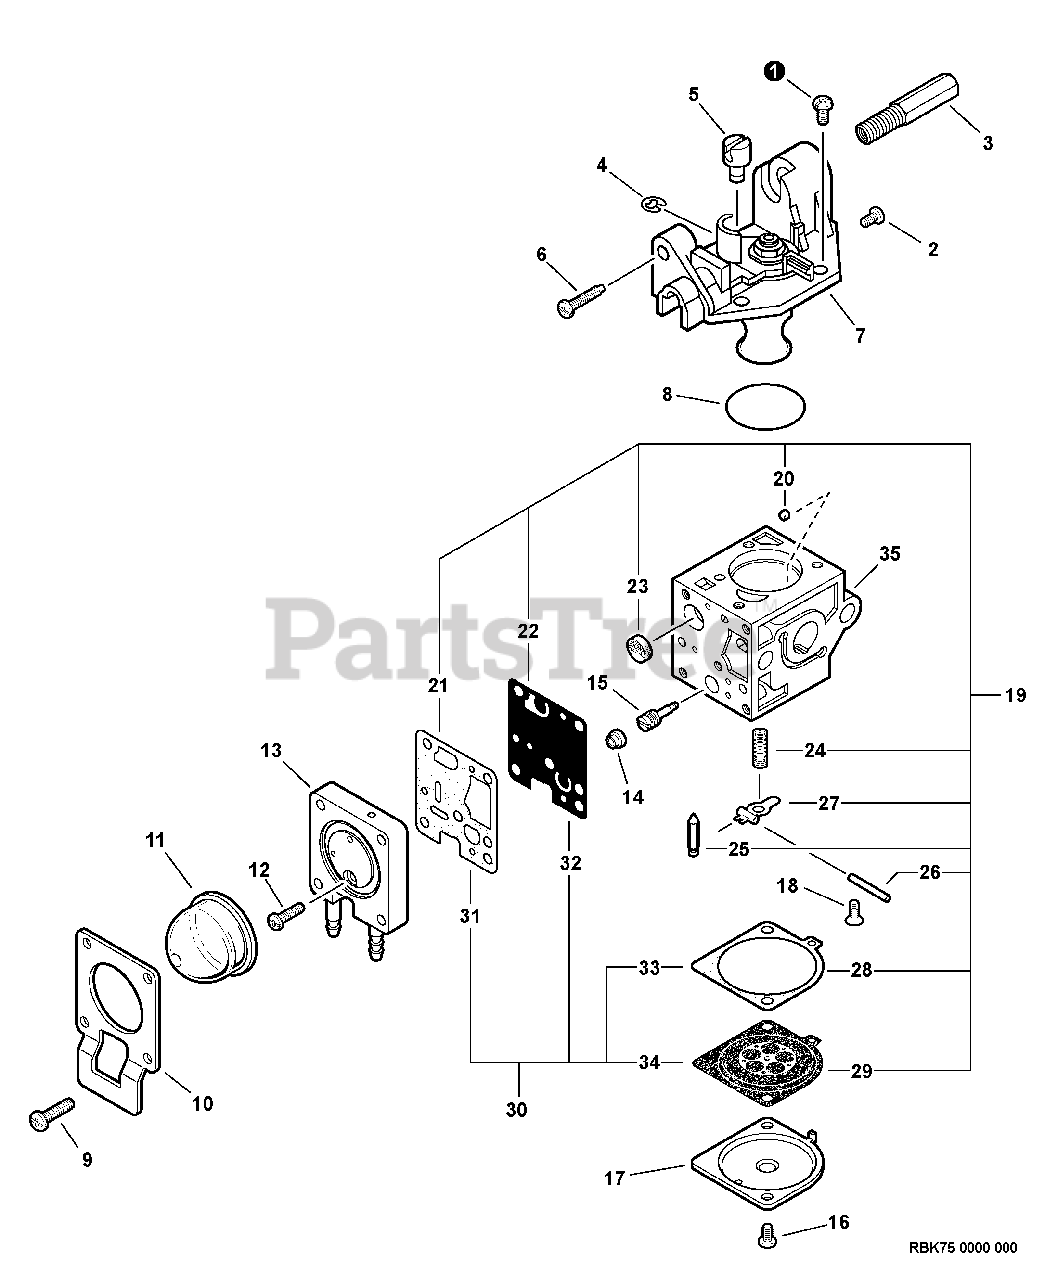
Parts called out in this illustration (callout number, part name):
3	NUT, CABLE ADJUST
4	RING, RETAINING
6	SCREW, IDLE ADJUST
7	ROTOR COVER ASSY
9	SCREW, RETAINER
10	RETAINER, PURGE BULB
11	BULB, PURGE
12	SCREW, PURGE BASE
13	BASE, PURGE
15	NEEDLE - HIGH SPEED
17	COVER, METERING
18	SCREW, METERING LEVER PIN
19	REPAIR KIT
20	GUIDE, ROLLER
21	GASKET, PUMP
22	DIAPHRAGM, PUMP
23	STRAINER
24	SPRING, METERING LEVER
25	VALVE, INLET NEEDLE
26	PIN, METERING LEVER
27	LEVER, METERING
28	GASKET, DIAPHRAGM
29	DIAPHRAGM, METERING
30	DIAPHRAGM/GASKET KIT
31	GASKET, PUMP
32	DIAPHRAGM, PUMP
33	GASKET, DIAPHRAGM
34	DIAPHRAGM, METERING
35	BODY, CARBURETOR
